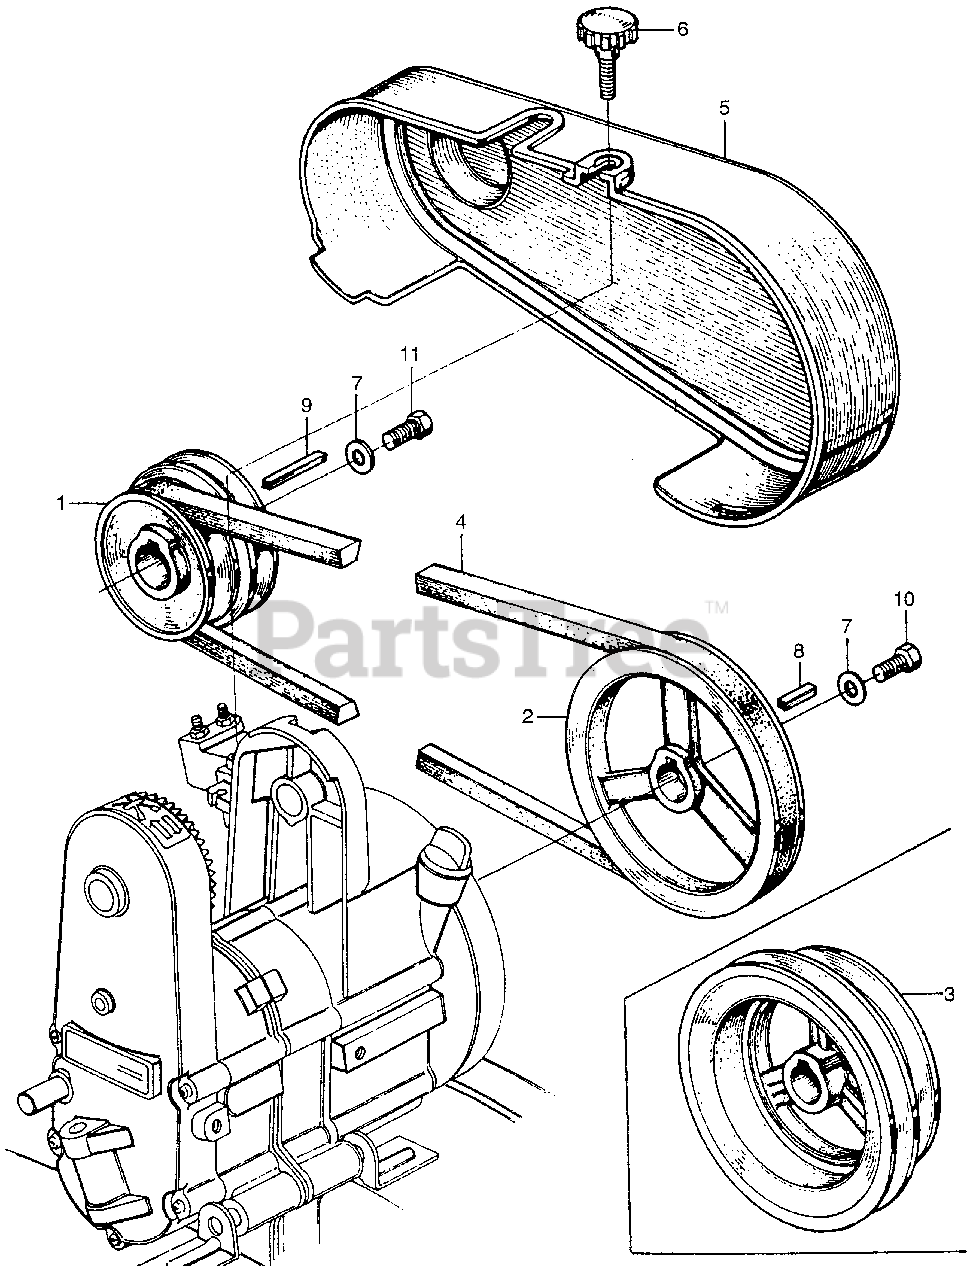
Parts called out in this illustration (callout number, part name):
1	PULLEY, DRIVE (NOT AVAILABLE)
2	PULLEY, DRIVEN
3	PULLEY, DRIVEN
4	V-BELT (RE-MF-6269) (MITSUBOSHI)
5	COVER, BELT *NH31* (MCKINLEY WHITE) (NOT AVAILABLE)
6	LATCH, BELT COVER (NOT AVAILABLE)
7	WASHER (8MM)
8	KEY, FLAT (4X4X14)
9	KEY (5X5X33)
10	BOLT, HEX. (8X16)
11	BOLT, HEX. (8X25)
